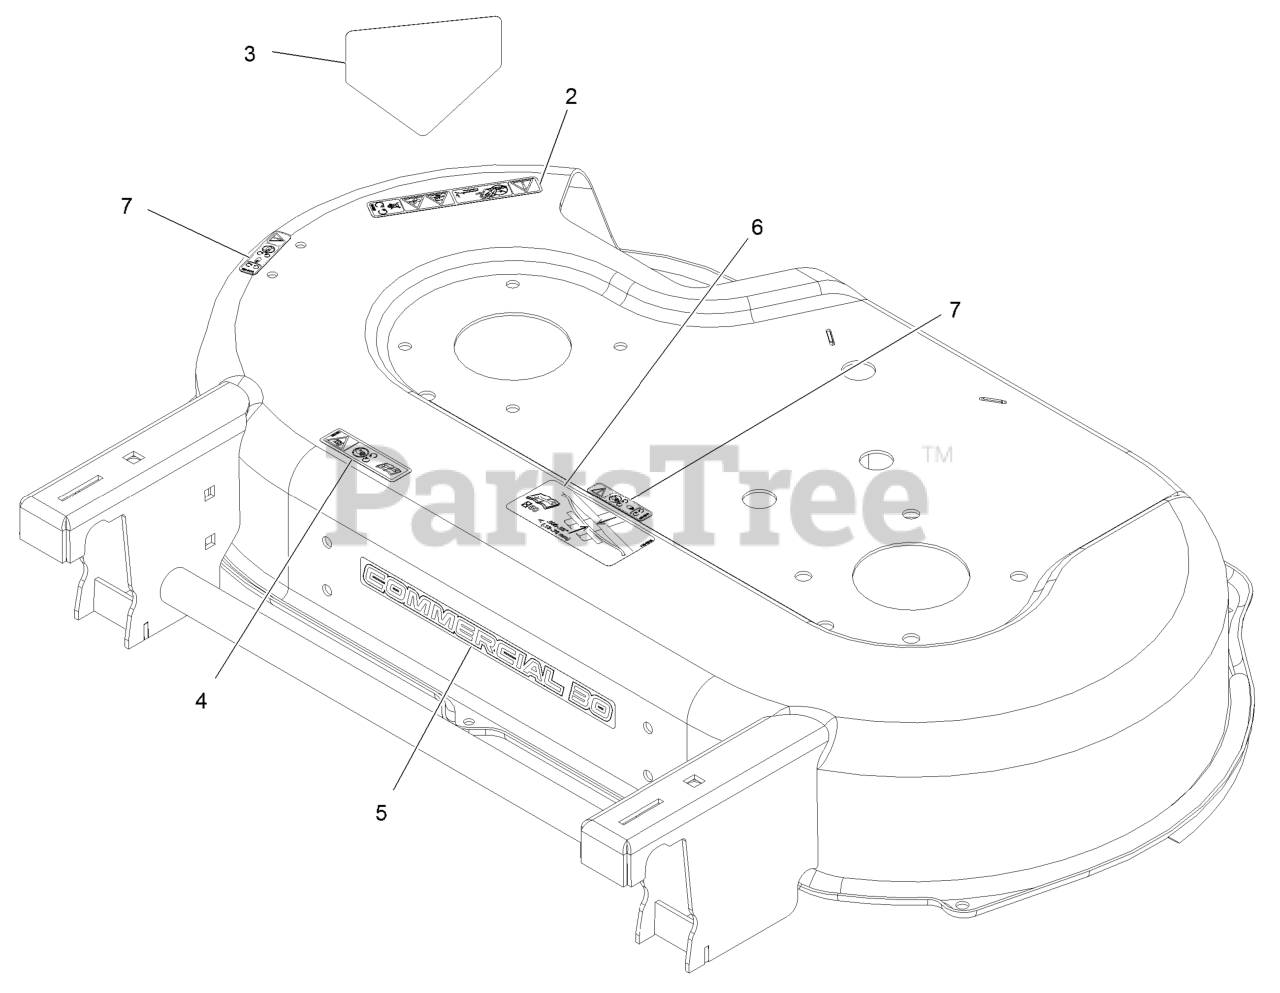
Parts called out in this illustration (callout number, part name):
2	DECAL-DANGER
3	DECAL-DANGER
4	DECAL-WARNING
5	DECAL-COMMERCIAL 30
7	DECAL-WARNING
